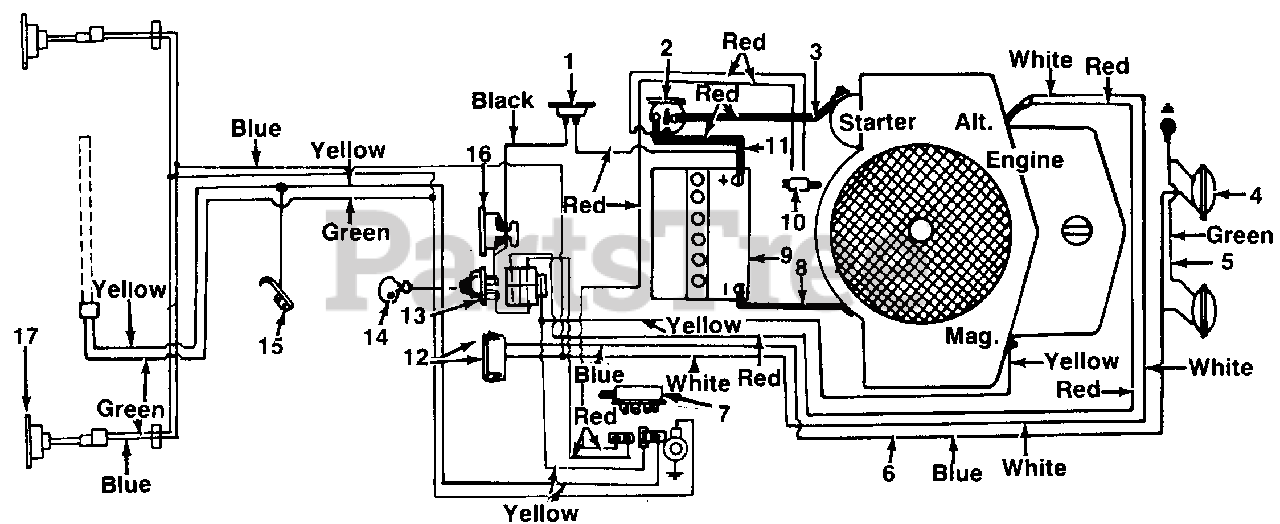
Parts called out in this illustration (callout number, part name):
1	Circuit Breaker
2	Solenoid
3	Wire
4	Headlight
5	Ground Wire
6	Wire Harness
7	Safety Switch
8	6 Ga. Black Wire
9	12V Battery
10	Safety Switch
12	Light Switch
13	Ignition Switch
14	Ignition Key
15	Spring Switch
16	Ammeter
17	Taillights
